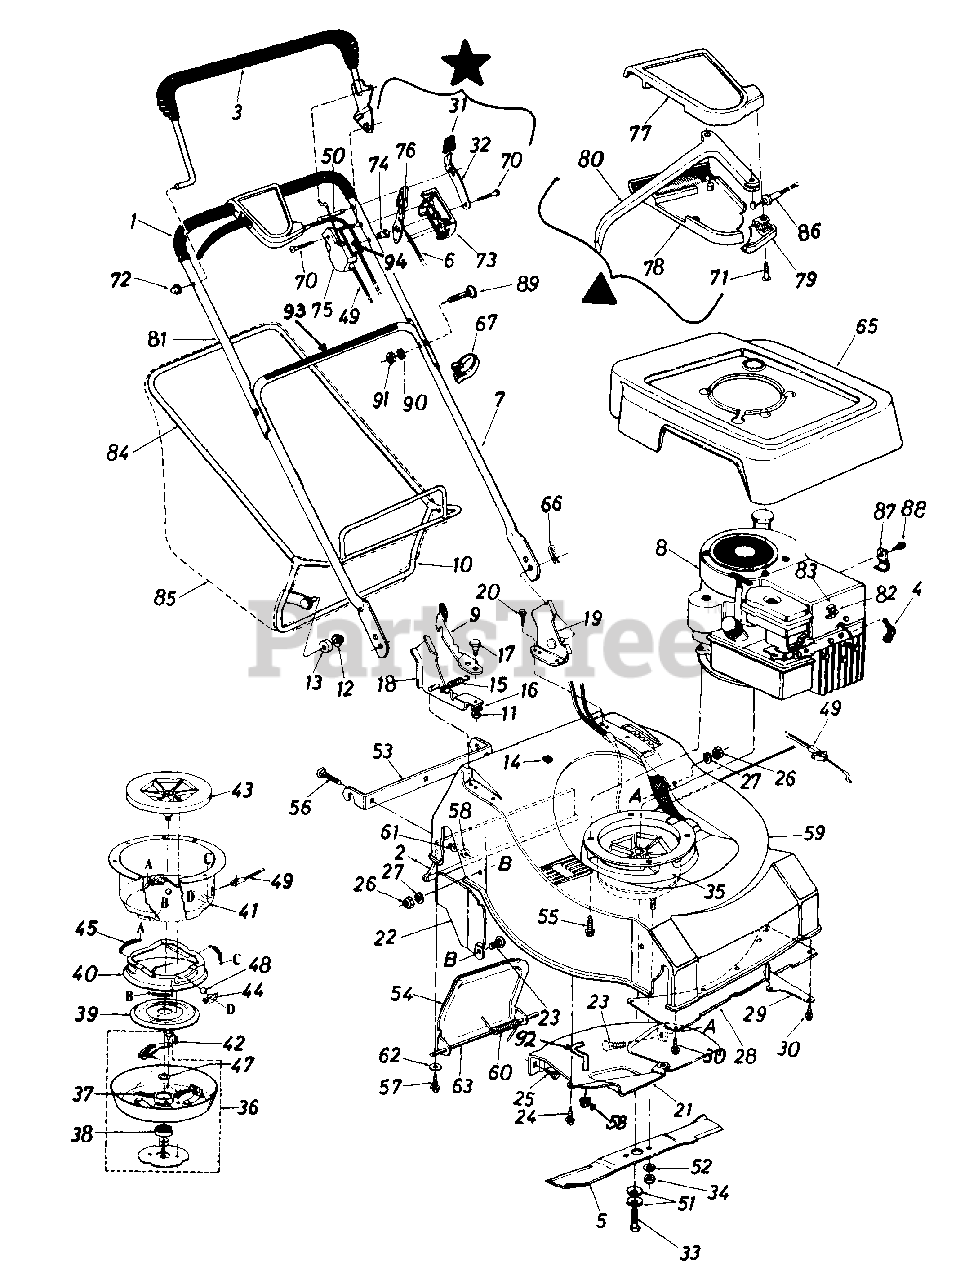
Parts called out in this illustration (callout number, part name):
2	Rear Flap Ass'y.
3	Control Handle - L.H.
4	Spark Plug Insulator
5	22" Blade
6	Throttle Wire - 58.0"
7	Lower Handle
8	Engine
9	Grass Catcher Lock Lever
12	Push Nut 3/8" Rod
13	Plastic Roller
15	Extension Spring
16	L-Wash. 5/16" I.D.
17	Shld. Bolt .437" Dia. x .162" Lg.
18	Handle Brkt. Ass'y. - R.H.
19	Handle Brkt. Ass'y. - L.H.
20	Hex Hd. Self-Tap Scr. 1/4-20 x 1.00" Lg.
21	Rear Baffle - L.H.
22	Side Baffle
23	Carriage Bolt 1/4-20 x .50" Lg.
24	Hex Wash. Hd. AB-Tap Scr. 1/4 x .62" Lg.
25	Hex Wash. Hd. Drill Scr. 1/4 x .75" Lg.
26	Hex Nut 1/4-20 Thd.
27	L-Wash. 1/4" I.D.
28	Front Cover Plate
29	Left Strap
30	Hex Wash. Hd. AB-Tap Scr. 1/4 x .62" Lg.
31	Spring Lever Knob
32	Lockout Spring
33	Hex Bolt 3/8-24 x 2.00" Lg. (Grade 8)
34	Hex Nut 3/8-24 Thd. (Grade 8)
35	Blade Brake Clutch Ass'y. Comp.
36	Clutch Blade Housing Ass'y.
37	Compression Spring .35" O.D. x 2.00" Lg.
38	Ball Brg. .669" I.D. x 1.574" O.D. x .47
39	Clutching Cone
40	Brake Cup Cone
41	Clutch Housing
42	Hex TT-Tap L-Scr. 1/4-20 x .75" Lg.
43	Fan Adapter
44	Ball Block
45	Extension Spring .35" O.D. x 1.75" Lg.
47	Fl-Wash. .690" I.D. x 1.060 O.D. x .030
48	Steel Ball .500" Dia.
49	Clutch Cable - 46.0"
50	Lock Pin .314" Dia. x 1.70
51	Bell-Wash. .400" I.D. x .88" O.D.
52	L-Wash. 3/8" I.D.
53	Grass Catcher Hitch Brkt.
54	Chute Door
55	Hex Wash. Hd. TT-Tap Scr. 3/8-16 x 1.00" Lg.
56	Carriage Bolt 1/4-20 x .75" Lg.
57	Hex Wash. Hd. "AB"-Tap Scr. 1/4 x .62"
58	Sems Nut 1/4-20 Thd.
59	22" Deck Ass'y.
60	Torsion Spring .34" I.D. x 2.38" Lg.
61	Fl-Wash. .281" I.D. x .73" O.D. x .063
62	Fl-Wash. .285" I.D. x 1.25" O.D. x .060
63	Rod .25" Dia. x 8.25" Lg.
65	Shroud Ass'y.
66	Intern. Cot. Pin 5/16" Dia.
67	Cable Tie
70	Truss Mach. B-Tap Scr. #12 x 1.50" Lg.
71	Flat C-Sunk AB-Tap Scr. #10 x .75" Lg.
72	Cap Speed Nut 5/16" Rod
73	Control Panel Half
74	Control Disc Pin
75	Clutch Panel Half
76	Throttle Control Lever
77	Control Cover Half - Upper
78	Control Cover Half - Lower
79	Cable Mtg. Cap
80	Control Lever
81	Upper Handle
82	Hex B-Tap Scr. #10 x .38
83	Casing Clamp
84	Grass Catcher Upper Frame
85	Grass Bag
86	Self-Propelled Clutch Cable - 50.0" Lg.
87	Casing Clamp
88	Hex B-Tap Scr. #10 x .38" Lg.
89	Curved Carriage Bolt 5/16-18 x 1.38" Lg.
90	L-Wash. 5/16" I.D.
91	Hex Nut 5/16-18 Thd.
92	Pulley Scraper Finger
93	Control Label - Handle
94	Control Label - Throttle
